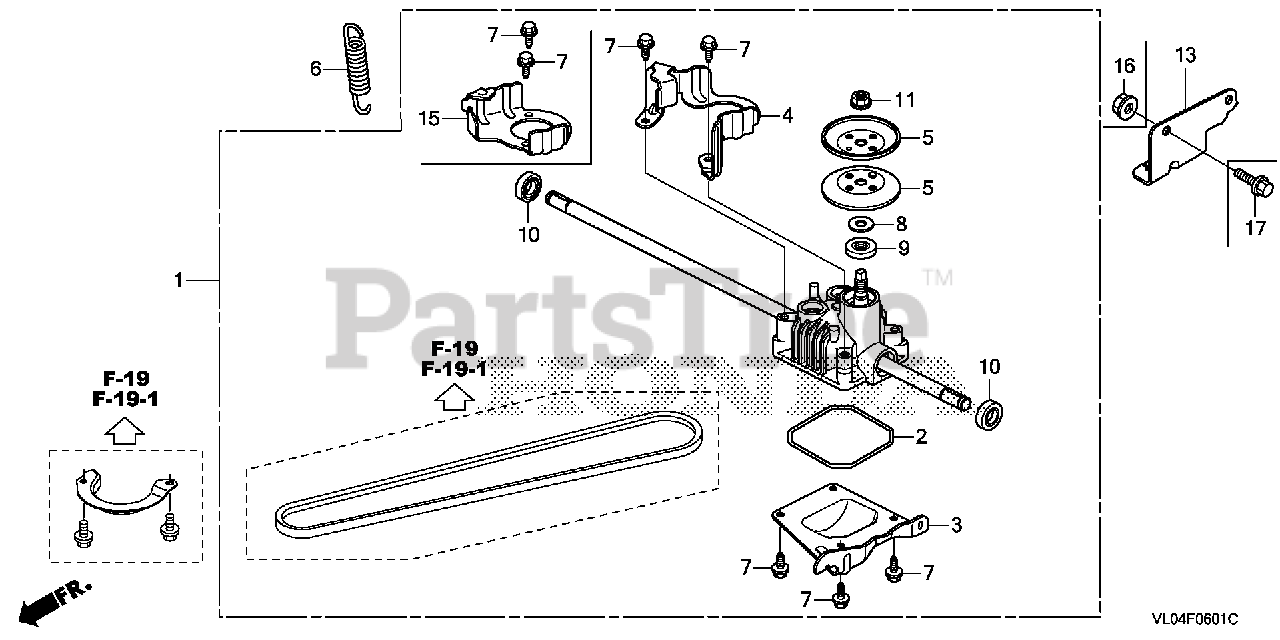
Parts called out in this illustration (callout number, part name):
1	TRANSMISSION ASSY.
2	O-RING, CASE
3	COVER, REDUCTION
5	FACE, DRIVEN
6	SPRING, WHEEL TENSION
7	BOLT, FLANGE (6X12) (CT200)
8	WASHER (10X24)
9	OIL SEAL (12.7X28.6X6.4)
10	OIL SEAL (12.7X22.2X6.4)
11	NUT, FLANGE (10MM)
13	BRACKET, CABLE MOUNT
15	GUIDE, BELT
16	NUT, FLANGE (8MM)
17	BOLT, FLANGE (8X16)
